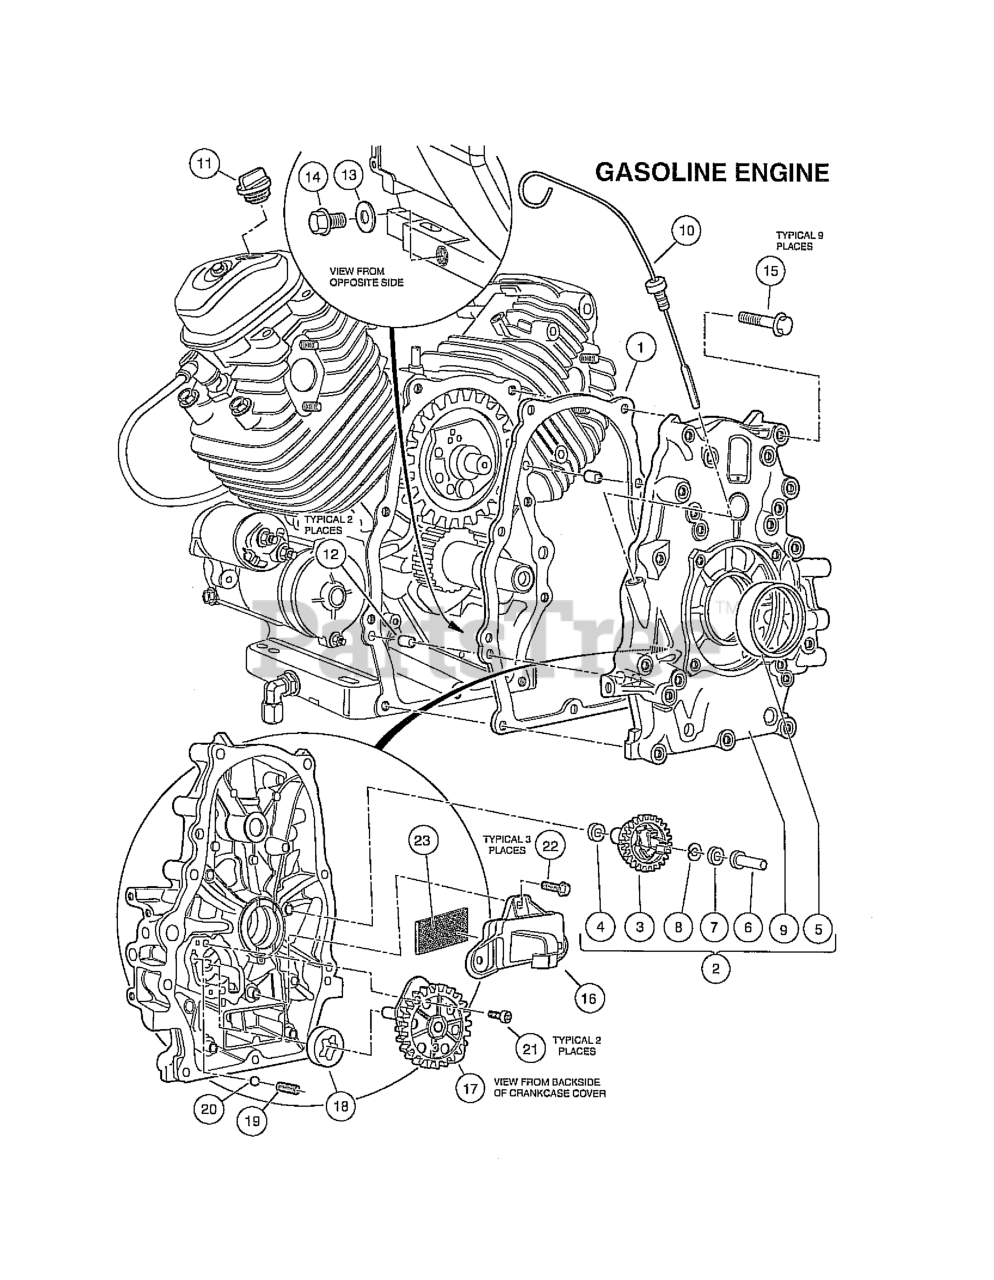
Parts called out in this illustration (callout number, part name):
1	GASKET, CASE COVER
2	COVER ASSY., CRANKCASE
3	GOVERNOR ASSY.
4	WASHER, PLAIN, M6
5	SEAL, OIL, 38 X 58 X 9
6	SLIDER, GOVERNOR
7	WASHER, 6 X 16
8	CLIP, GOVERNOR
10	DIPSTICK, OIL
11	CAP, OIL FILLER
12	PIN A, DOWEL, 8 X 14
13	WASHER, DRAIN PLUG, M14
14	BOLT, DRAIN PLUG, M14
15	BOLT, FLANGE, M8 X 1.25 X 50
16	COVER, OIL FILTER
17	COVER ASSY., OIL PUMP
18	ROTOR, OIL PUMP, OUTER
19	SPRING, RELIEF VALVE
20	BALL, STEEL, 3/8, #12
21	BOLT, SOCKET
22	BOLT, FLANGE, M6 X 1 X 20
